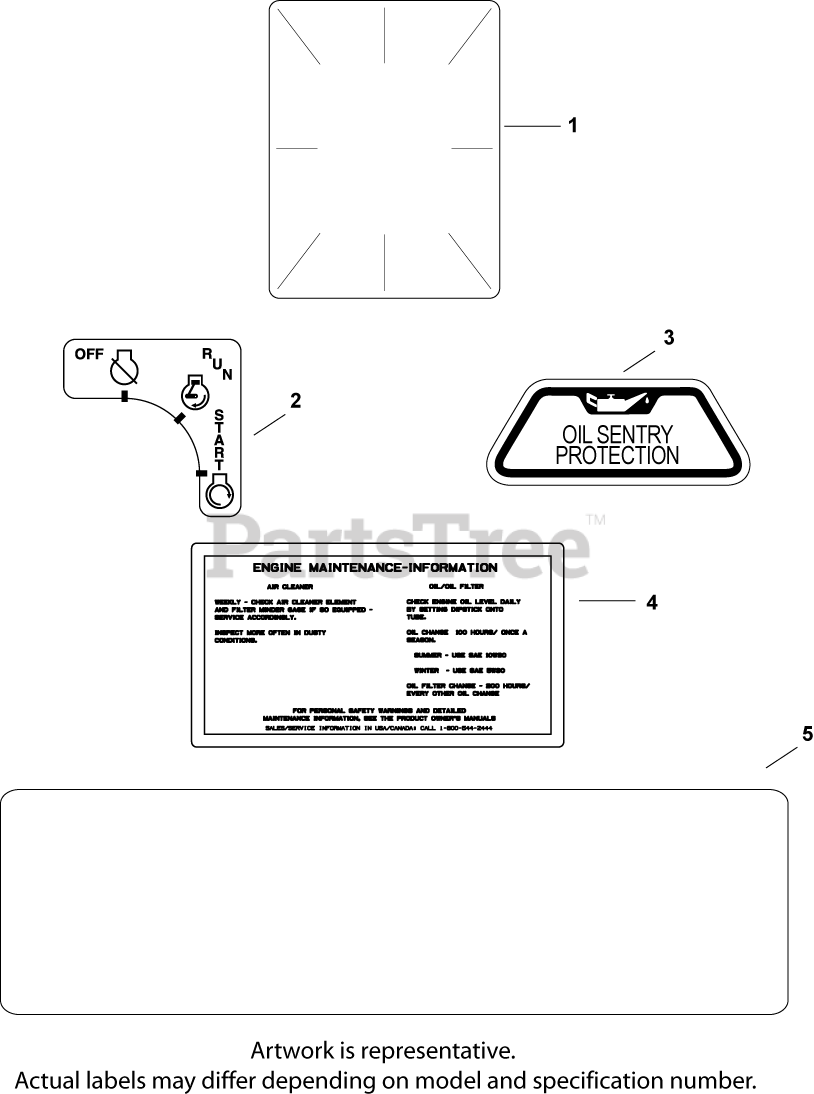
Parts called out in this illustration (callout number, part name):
1	DECAL, CLEAR LAMINATE USE 25 113 70-S
2	DECAL, KEY SWITCH
3	DECAL, OIL SENTRY - (#DSC)
4	DECAL, AIR CLEANER - (#DSC)
5	DECAL, 23 HP - (#24113216S)
